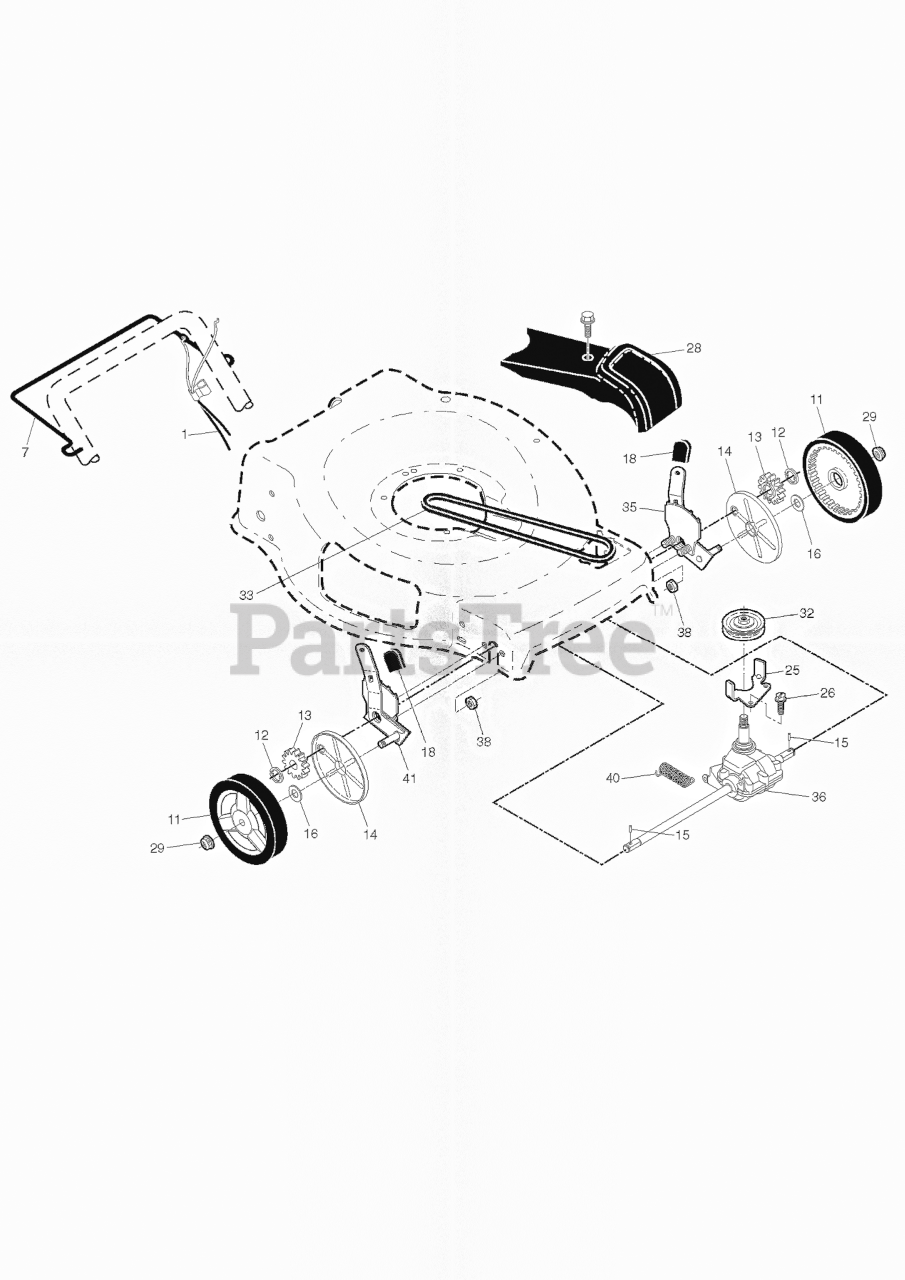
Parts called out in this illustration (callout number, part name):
1	CABLE.DRIVE.VS/SS.22+FGD.MCCUL
7	BAIL.CURVED.UNDER.BAIL.BLACK
11	WHEEL.8X1.75.H3SPK.RAD3.GY.BU3
12	E-RING 7/16 RE
13	PINION.14.TEETH.FGD
14	COVER.DUST.WHEEL.INNER.WALK
15	PAWL, DRIVE
16	WASHER FLUT
18	SELECTOR KNOB
25	BRACKET.BELT.GUIDE.22+FGD.BZP
28	COVER.DR.ASM.421097.HUSQ.CE
29	NUT.HEX.FLANGE.3/8-16.LO(3 2)
32	RP PULLEY.DRIVE.EZ/VAR.SCREWON
32	PULLEY.DRIVEN.EZ/VARI (2 2MC)
33	BELT.DRIVE.FGD.
35	ADJUSTER.ASM.22+FGD.LF /AWD LT
36	TRANSMISSION.22+.FWGD.SS/VS
38	NUT.HEX.FLANGE.1/4
38	NUT.FLANGE.1-4-20-SERR
41	ADJUSTER.ASM.22+FGD.RF /AWD RT
